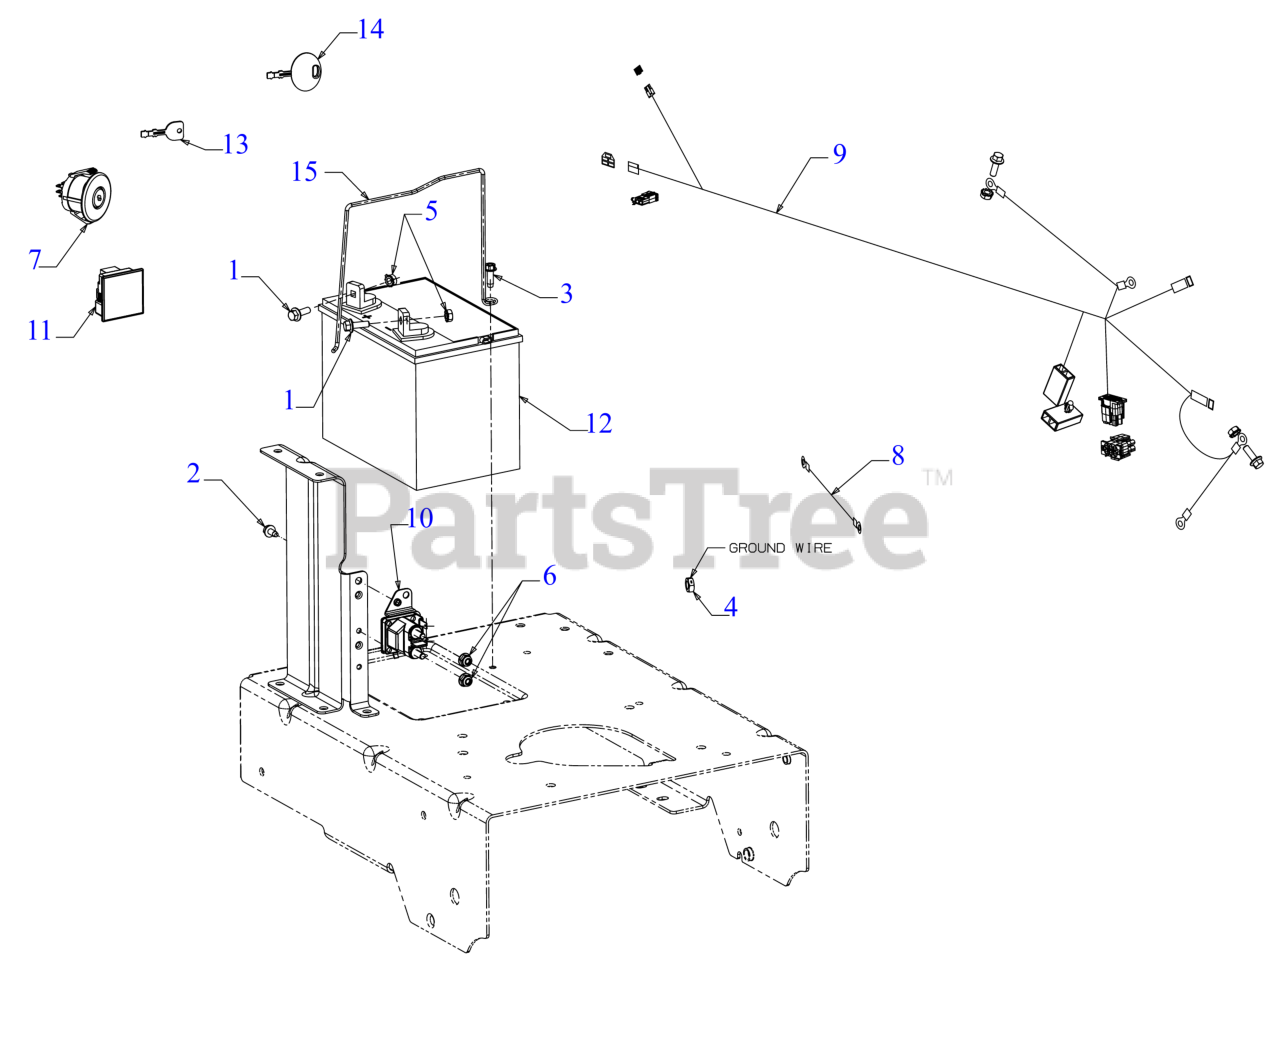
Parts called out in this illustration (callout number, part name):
1	SCREW 1/4-20 x .75 GR5
2	SCREW 1/4-20 X.500
3	SCREW 1/4-20 x .750
4	JAM LOCK NUT
5	SEMS NUT 1/4-20
6	SEMS NUT 1/4-20
7	KEY SWITCH 3 POS
8	STARTER HARNESS
9	MAIN WIRE HARNESS
10	12V SOLENOID
11	HOUR METER/SERVICE MINDER
11	Cub Cadet HOUR METER KIT
11	Troy-Bilt HOUR METER KIT
12	Purchase Battery Locally
12	BATTERY
13	IGNITION KEY
15	BATTERY HOLD DOWN STRAP
